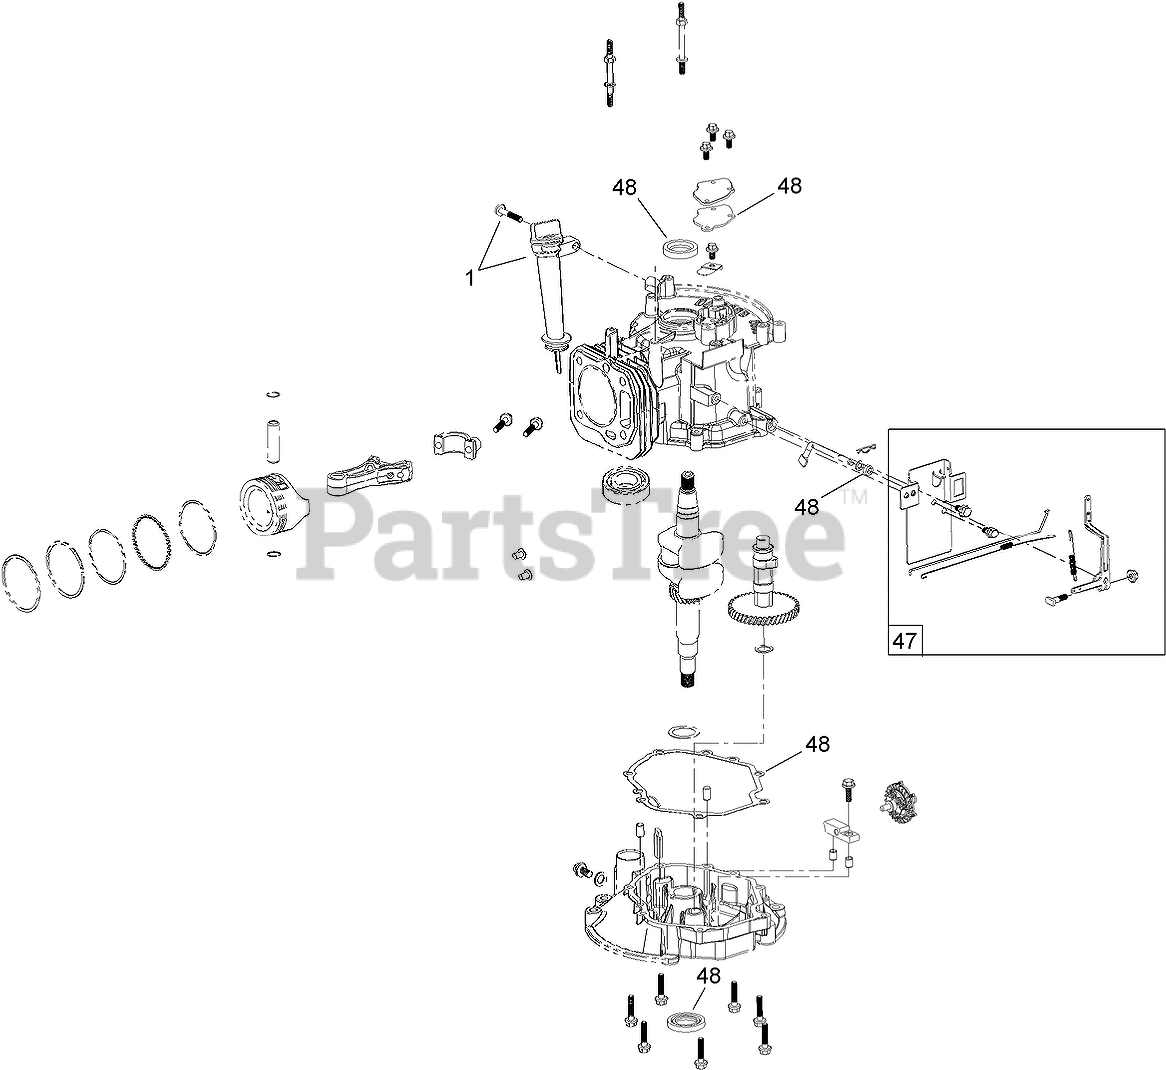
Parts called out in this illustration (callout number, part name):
1	DIPSTICK AND FILL TUBE KIT
47	GOVERNOR ARM KIT
48	SEAL AND GASKET KIT
